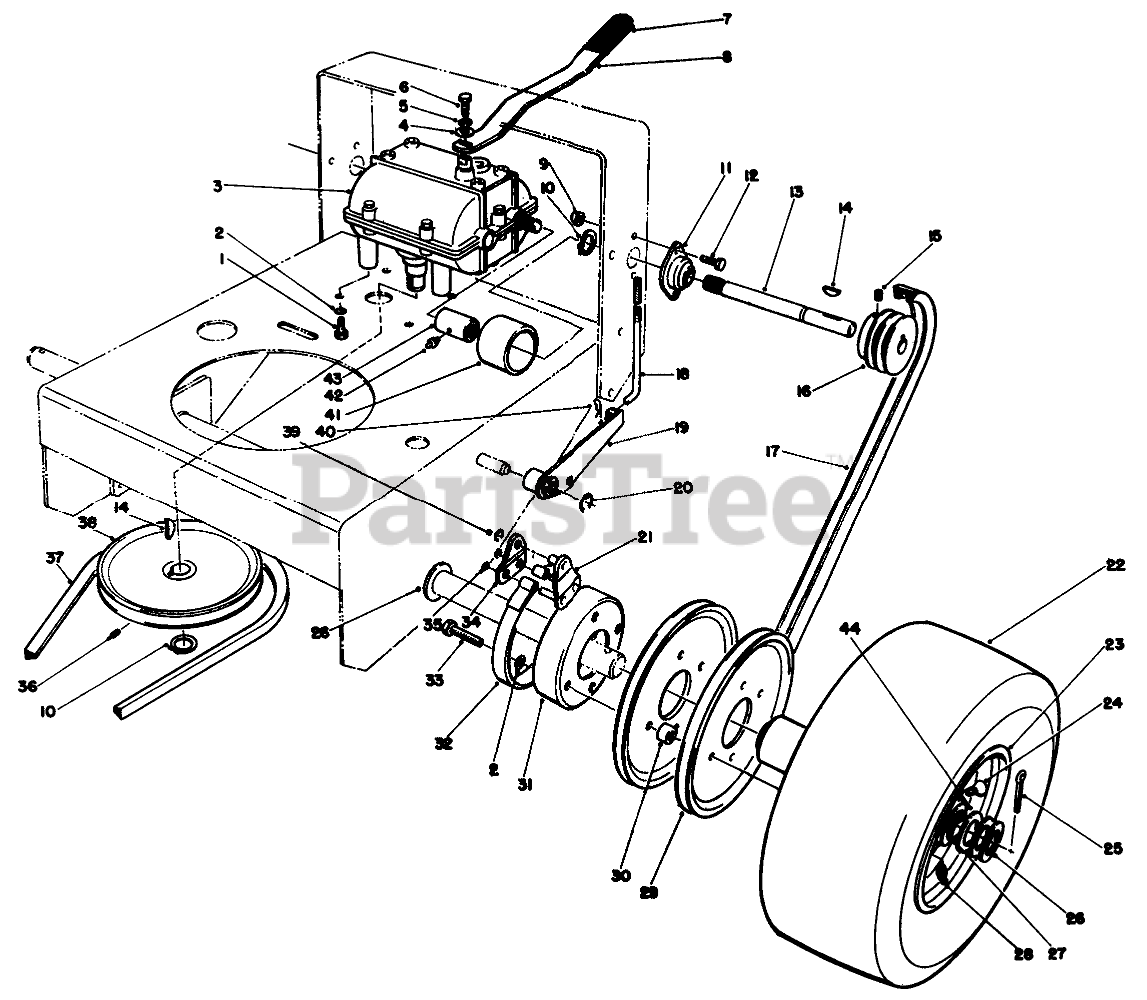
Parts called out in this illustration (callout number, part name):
1	SCREW-HH
2	WASHER-LOCK
3	Transmission
4	SPACER
5	WASHER-LOCK
6	SCREW-HH
8	LEVER-SHIFT
9	NUT-LOCK, NI
10	RING-SNAP, EXTERNAL
11	BEARING-EXTERNAL SHAFT
12	SCREW-HH
13	SHAFT-EXTENSION, RH
14	KEY-WOODRUFF
15	SCREW-SET, HSH
16	Pulley-Drive
17	V-BELT
18	ROD-BRAKE
19	Brake Arm-LH
20	RING-RETAINING
21	LINK-BRAKE
23	WHEEL AND HUB ASM
24	STEM-VALVE
25	PIN-COTTER
26	WASHER-WHEEL
27	BEARING-BALL, FLANGED
28	FITTING-LUBE, 45 DEG
29	Pulley-Wheel
30	SPACER-PULLEY
31	Drum-Brake
32	BAND-BRAKE
33	SCREW-HH
34	Plate-Link
35	RING-RETAINING
36	SCREW-SET
37	V-BELT
38	PULLEY-DRIVEN
39	RING-RETAINING, EXTERNAL
40	PIN-COTTER
41	GUARD-COUPLER
42	FITTING-GREASE
43	COUPLER
44	WASHER-THRUST
